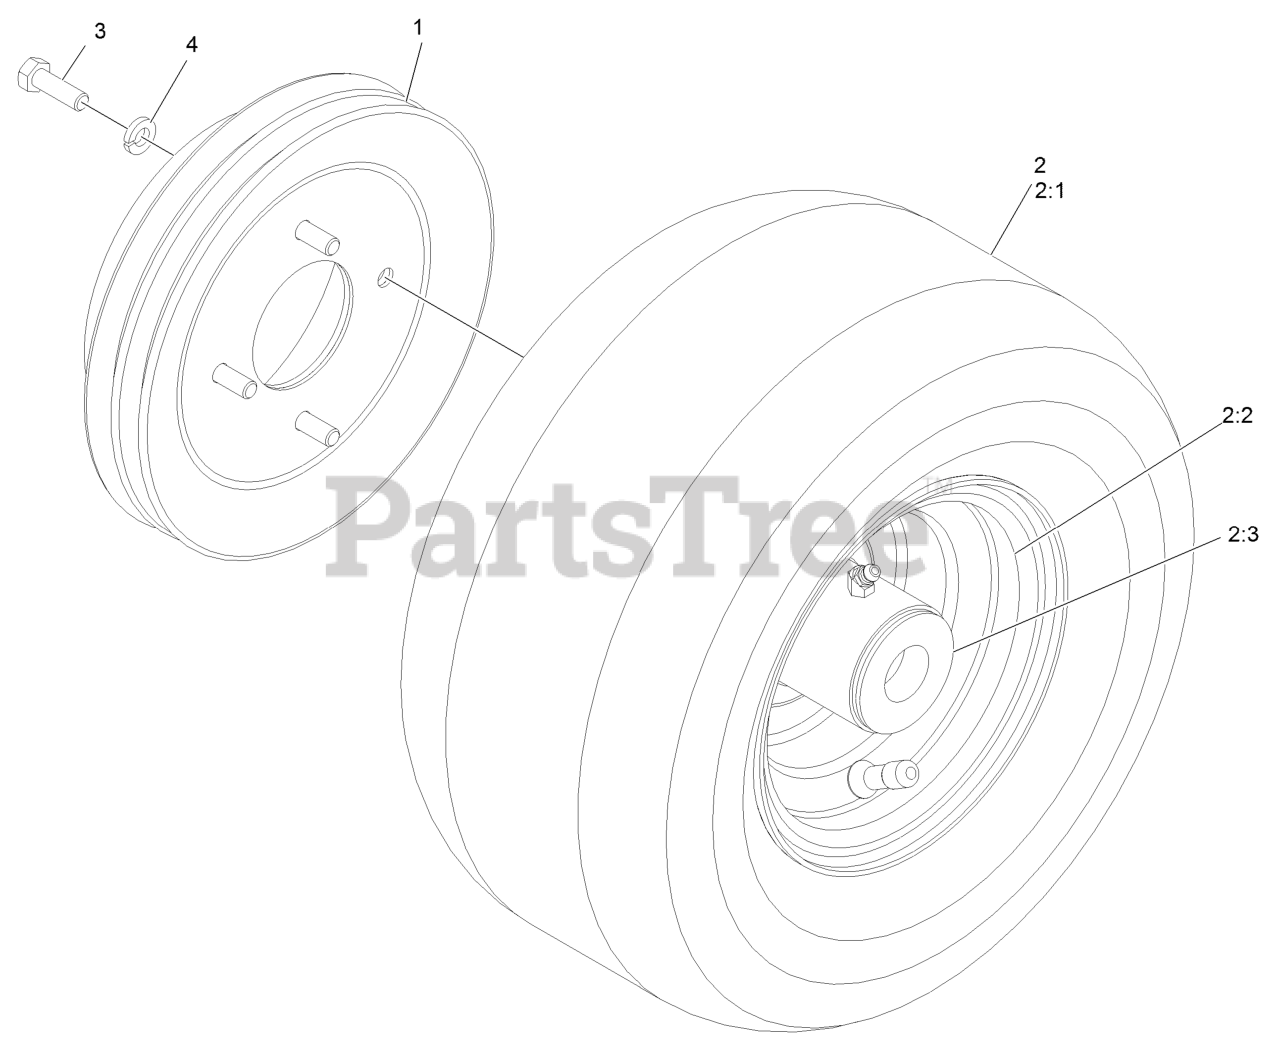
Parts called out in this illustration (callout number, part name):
1	DRUM AND SHEAVE ASM
2	WHEEL AND TIRE ASM
2:1	TIRE
2:2	WHEEL AND HUB ASM
2:3	BEARING-FLANGED
3	SCREW-HH
4	WASHER-LOCK
